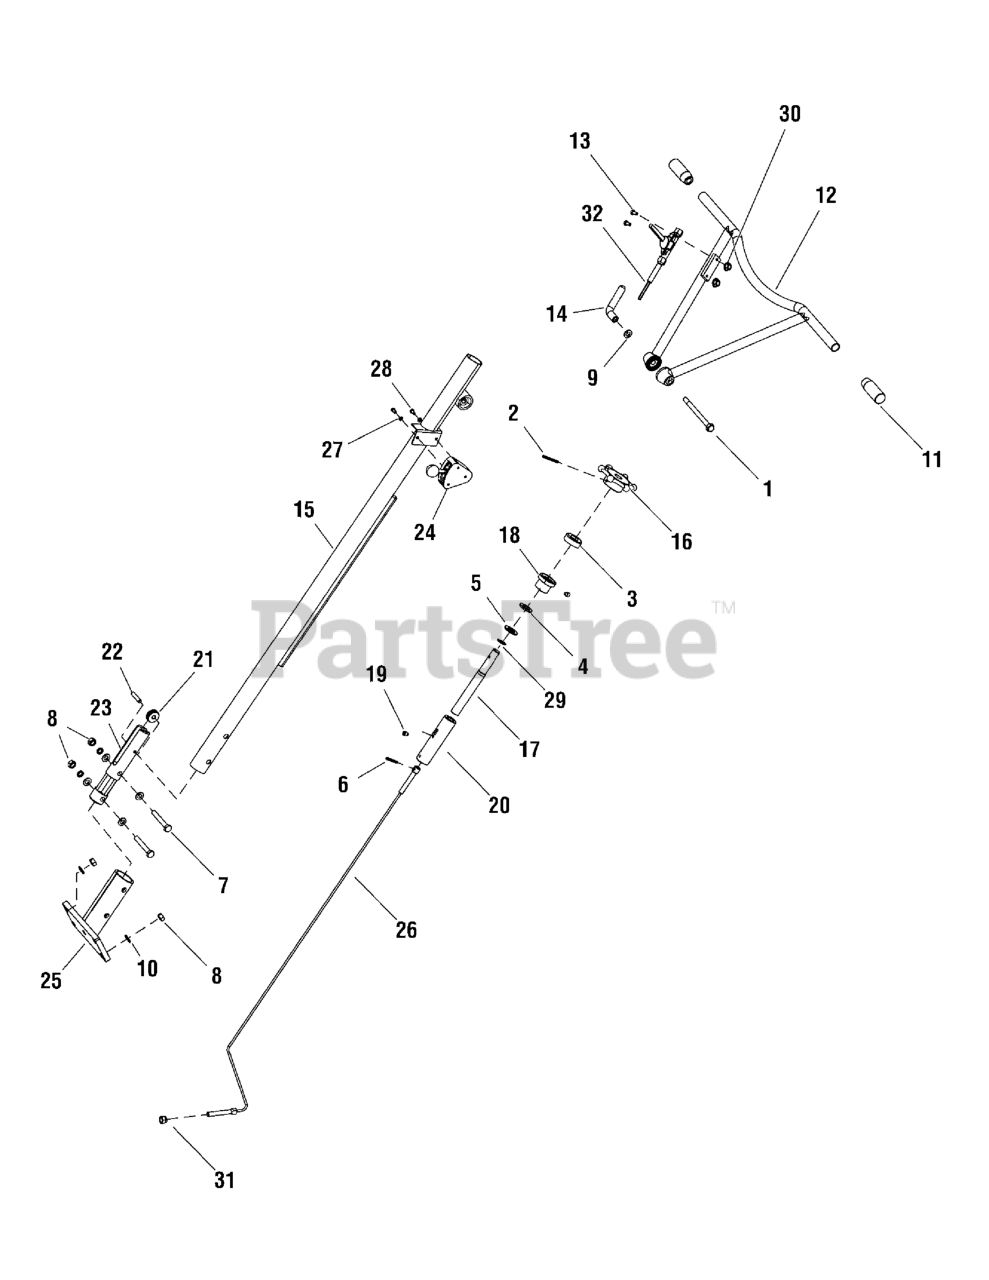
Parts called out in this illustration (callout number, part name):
1	BOLT, Hex Head, M10 x 120
2	PIN, Parallel, 5 x 50
3	THRUST BALL BEARING
4	WASHER, Wave
5	WASHER, Plain
6	PIN, Spring Type, 5 x 35
7	BOLT, Hex, M10 x 70
8	NUT, Hex, M10
9	WASHER, Plain
10	WASHER, Spring
11	HANDLE, Rubber
12	HANDLE
13	THROTTLE ASSEMBLY
14	LOCKING HANDLE
15	CENTER JOINTING PIPE
17	ADJUST SCREW ROD
18	BUSHING
19	SCREW, Hex Socket Head, M6 x 8
20	ADJUST SCREW PIPE
21	ROLLER WHEEL
22	PIN, Taper, Internal Thread, 6 x 30
23	SHAFT, Roller Wheel
24	STOPPING DEVICE
25	HANDLE LINK PART
26	ADJUSTABLE WIRE
27	WASHER, Plain
28	SCREW, Pan Head, Cross Recessed, M5 x 10
29	CIRCLIP
30	NUT, Hex, Prevailing Torque, M10
32	SCREW, Hex Socket Head, Countersunk, M6 x 16
